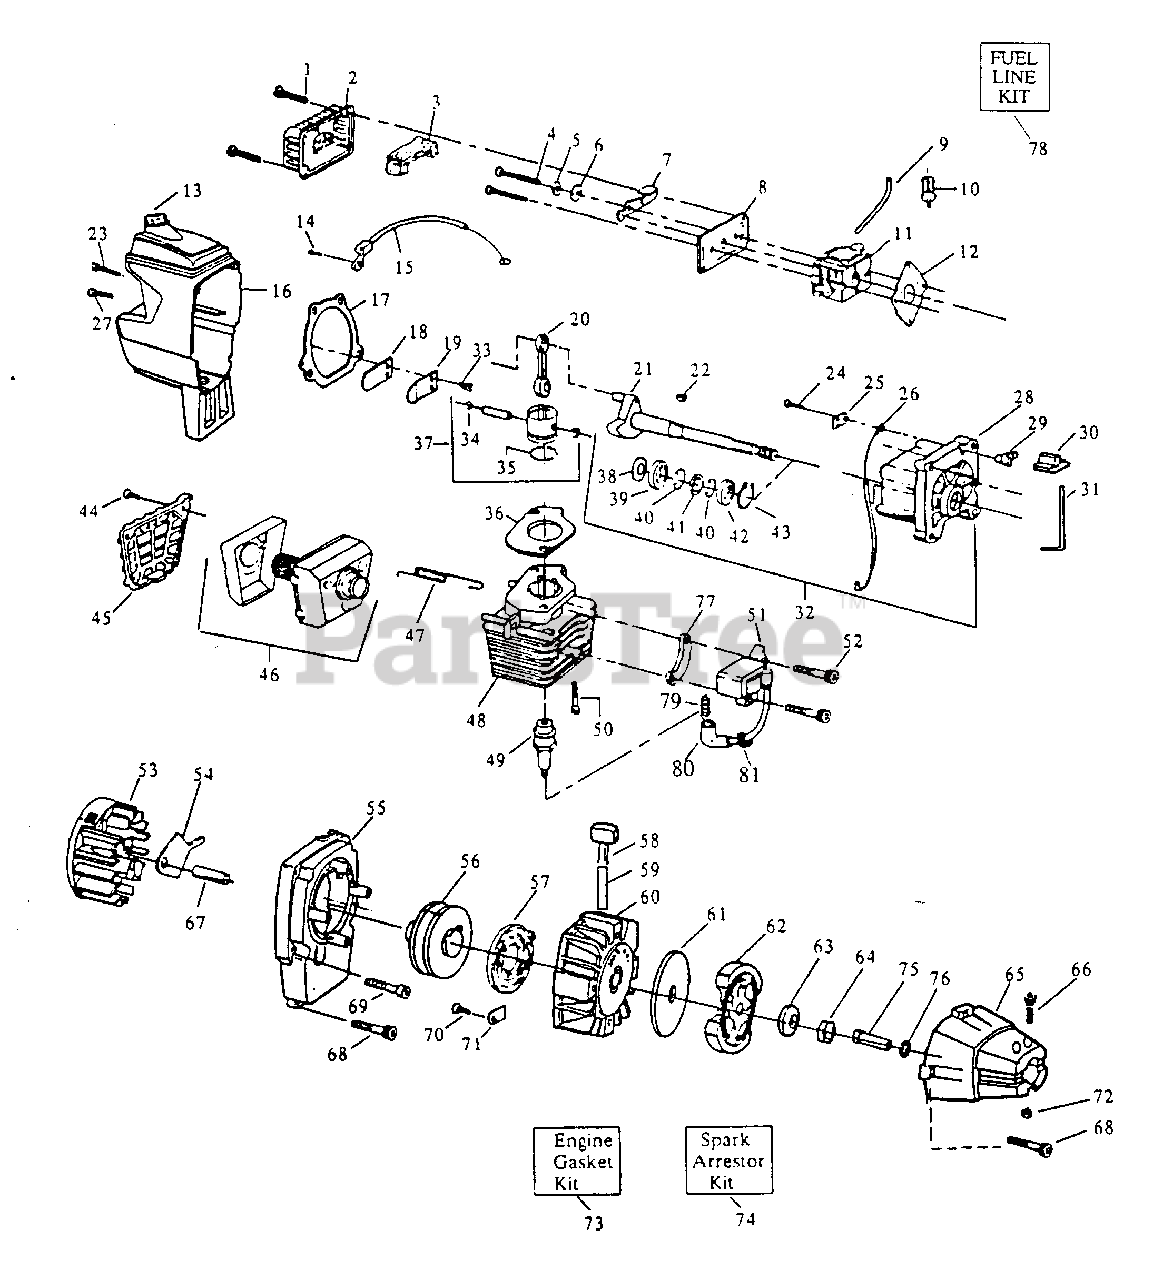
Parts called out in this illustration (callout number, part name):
2	Air Filter Cover
3	Air Filter
4	Screw
5	Spacer
6	Wave Washer
7	Choke Shutter
8	Air Filter Plate
9	Fuel Line Kit
10	Fuel Pick-up Assy.
11	Model XT-20,TT-20 (WA-207)
11	Model XT-50 (WA-199)
12	Carburetor Gasket
13	Fuel Cap Assy.
15	Model XT-20,TT-20
15	Model XT-50
16	Model XT-20
16	Model XT-50
17	Crankcase/Shroud Gasket
19	Reed Stop
20	Model XT-20,TT-20
20	Model XT-50
21	Model XT-20,TT-20
21	Model XT-50
22	Flywheel Key
25	Kill Switch Insulator
26	Lead Wire
28	Crankcase Assy. (Inc.39 - 42)
29	Kill Switch Ramp
30	Kill Switch Button
31	Kill Switch Spring
32	Model XT-20,TT-20
32	Model XT-50
34	Piston Pin Retainer
35	Model XT-20,TT-20
35	Model XT-50
36	Cylinder Gasket
37	Model XT-20,TT-20
37	Model XT-50
39	Inner Bearing
40	Retaining Ring
41	Crankshaft Seal
42	Outer Bearing
43	Crankshaft Retaining Ring
45	Muffler Guard
46	Muffler Kit
47	Muffler Attachment Spring
48	Model XT-20,TT-20
48	Model XT-50
49	Spark Plug
51	Ignition Module Kit
52	Model XT-20,TT-20
52	Model XT-50
53	Flywheel Assy.
54	Flywheel Counterweight
55	Model XT-20,TT-20
55	Model XT-50
56	Starter Pulley
57	Starter Spring
58	Starter Handle
59	Rope Kit
60	Pulley Housing Assy. Model XT-50
61	Clutch Washer Model XT-50
62	Clutch Assy. Kit Model XT-50
63	Washer Model XT-50
64	Nut Model XT-50
65	Clutch Housing Model XT-50
67	Spacer Model XT-50
71	Retainer
73	Engine Gasket Kit
74	Spark Arrestor Kit
75	Drive Coupling Model XT-20,TT-20
76	Washer Model XT-20,TT-20
77	Spacer Model XT-20,TT-20
78	Fuel Line Kit
79	Connector, Spark Plug
80	Boot, Spark Plug
81	Grommet - Plug Wire
